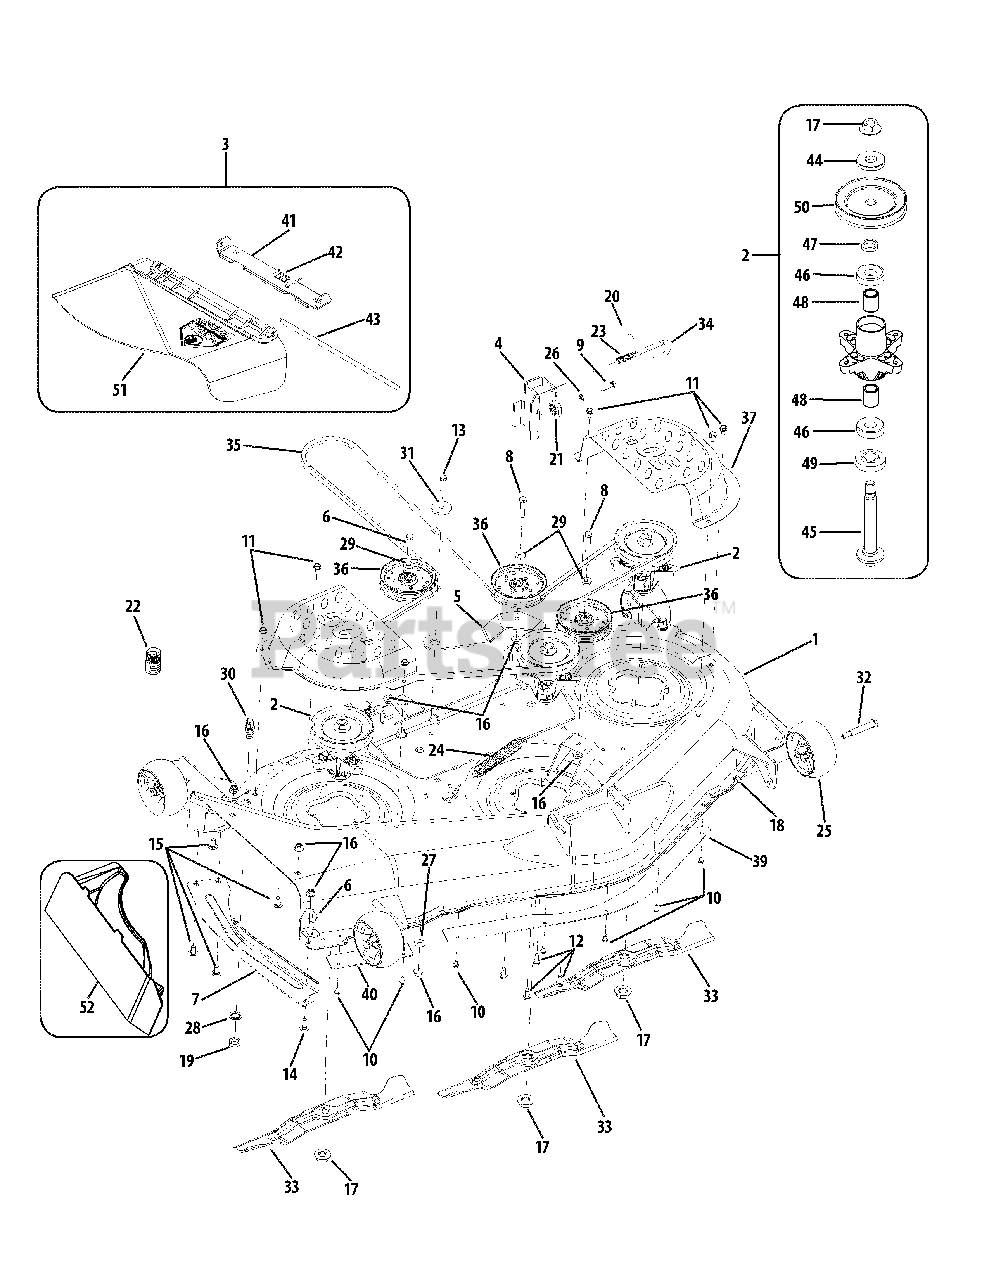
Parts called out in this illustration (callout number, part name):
2	Spindle Assembly
3	Discharge Chute Assembly
8	Hex Cap Screw, 3/8 -16 x 1.75
9	Hex Cap Screw, 5/16-18 x 1.25
10	Hex Washer Head Screw, 1/4-20 x .5
11	Hex Washer Head Screw, 5/16-12 x .75
12	Hex Washer Head Screw, 5/16-18 x .75
13	Hex Cap Screw, 3/8 -16 x 1.25
14	Carriage Screw, 3/8 -16 x 1.0
15	Carriage Screw, 3/8 -16 x .75
16	Hex Insert Flange Lock Nut, 3/8-16
17	Hex Flange Nut, 5/8 -18
18	Hex Flange Lock Nut, 3/8 -16
19	Hex Nut, M16-1.5
20	Cotter Pin, 1/8 x 1.25
21	Deck Adjustment Gear
22	Water Nozzle Adapter
23	Compression Spring
24	Extension Spring, .94 Dia. x 6.74
25	Deck Ball Wheel, 5.0
26	Lock Washer, 5/16
27	Bell Washer, .45 x 1.0 x .062
28	Internal Tooth Lock Washer, 5/8
29	Flat Washer, .38 x .93 x .110
30	Deck Wash Nozzle
31	Shoulder Spacer, .884 x .190
32	Shoulder Screw, .5 x 2.5 x 3/8 -16
33	Blade, 2 in 1, 17.9
34	Deck Hanger Rod
35	V-Belt Type A Sec x 134
36	Idler Pulley, 4.25 Dia
41	Chute Mounting Bracket
42	Torsion Spring
43	Hinge Pin
44	Flat Washer, .76 x 1.50 x .12
45	Spindle Shaft, 5.75
46	Ball Bearing
47	Spacer, .79 x 1.25 x .175
48	Spacer, .80 x 1.10 x 1.32
49	Spacer, .79 x 1.82 x .55
50	V-Type Pulley, 5.39
51	Chute Deflector
52	Mulch Plug
